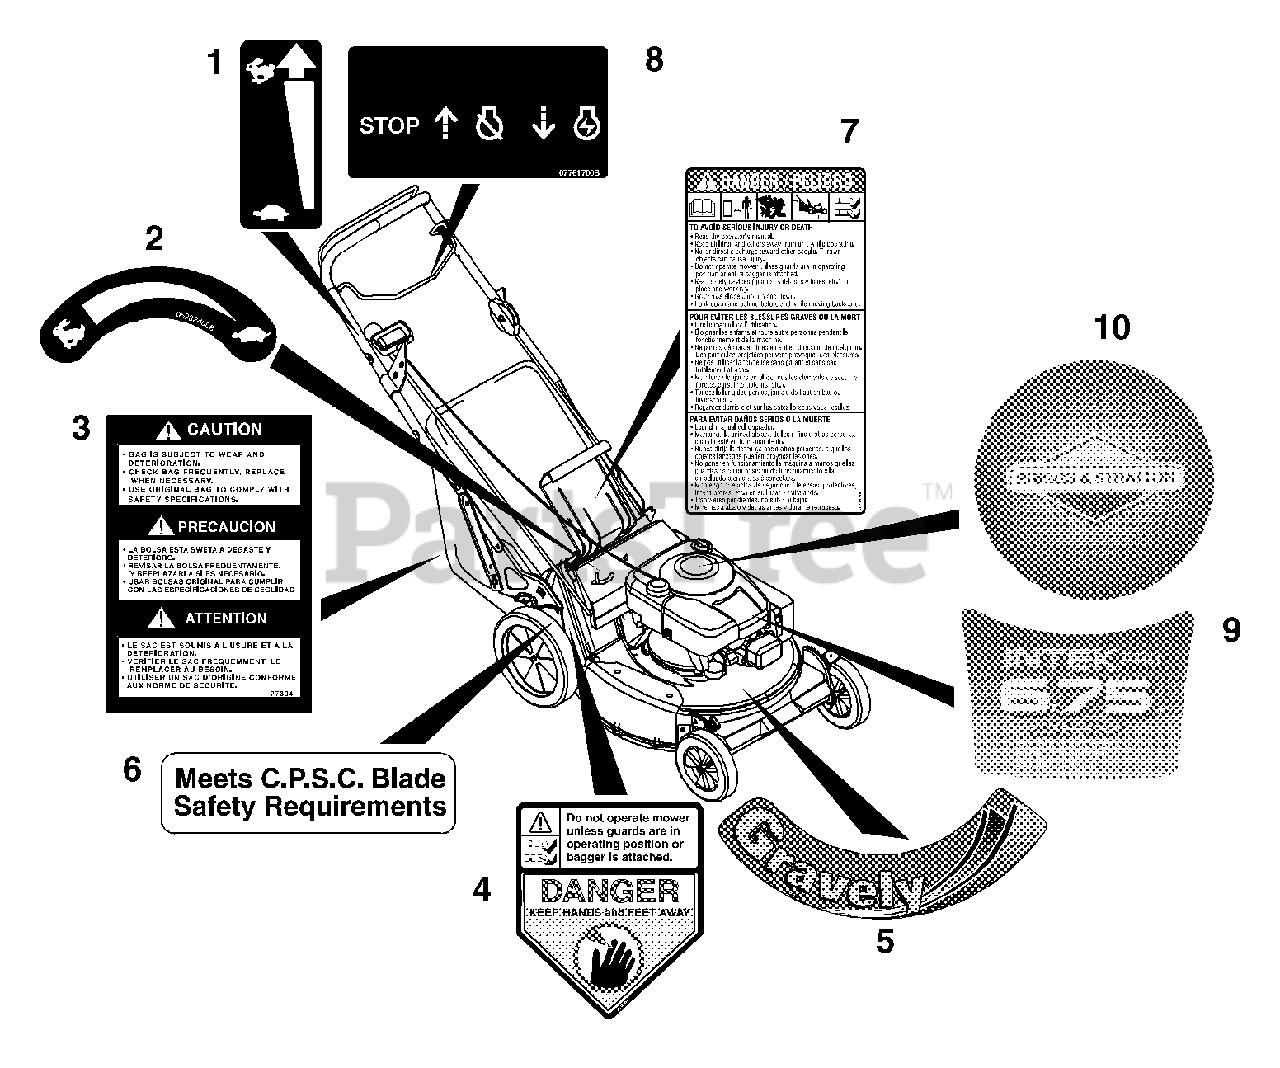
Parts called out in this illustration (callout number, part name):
1	Decal, Speed Control
2	Decal, Turtle and Rabbit
3	Decal, Bagger-21"
4	Decal, CPSC Danger
5	Decal, Commercial
6	Decal, C.P.S.C. Blade Safety
7	Decal, Bilingual Danger
8	Decal, Engine Control
9	Decal, Briggs and Stratton Intek Pro 6.75
10	Decal, Round Briggs and Stratton
